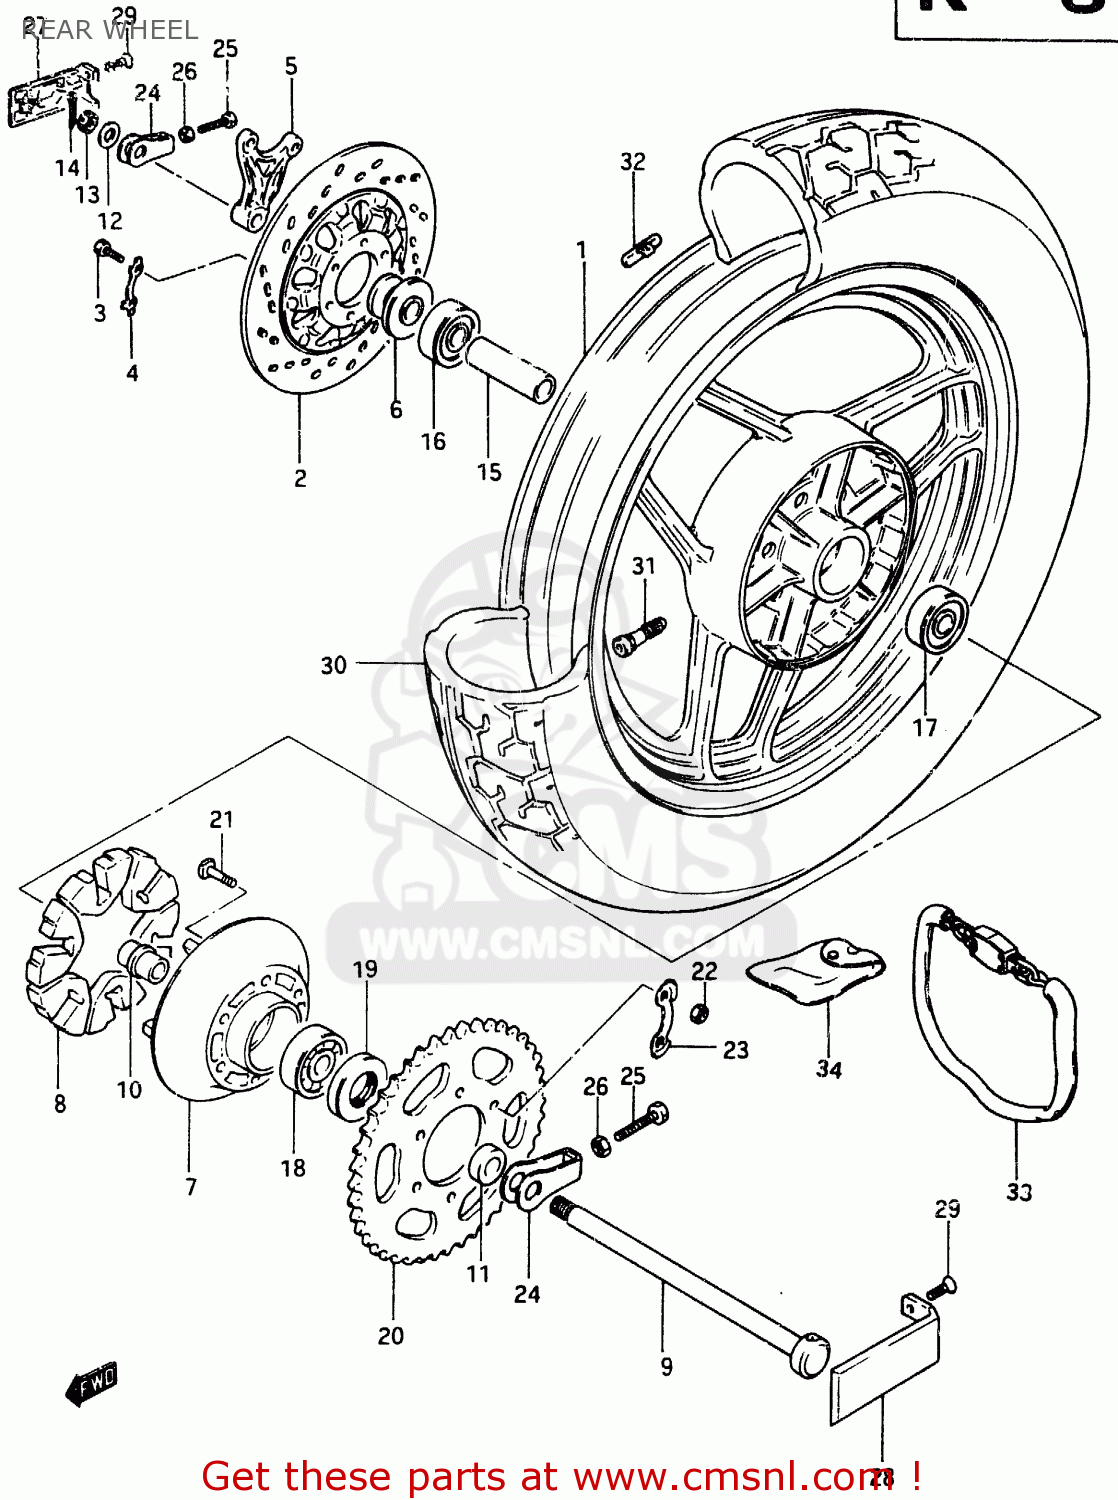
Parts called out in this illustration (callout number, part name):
1	CASTING WHEEL,GOLD
2	DISC,BRAKE
3	BOLT(8X30)
4	WASHER
5	BRACKET,REAR CALIPER
6	SPACER,REAR AXLE,RIGHT
7	DRUM,REAR SPROCKET MOUNT
8	ABSORBER,REAR HUB SHOCK
9	AXLE,REAR
10	RETAINER,RR SPROCKET DRUM
11	SPACER(17X33X11.3)
12	WASHER
13	NUT
14	PIN,COTTER
15	SPACER(17.5X25X88)
16	BEARING
17	BEARING
18	BEARING
19	SEAL,OIL(33X62X7)
20	SPROCKET,REAR
21	BOLT(10X35.5)
22	NUT
23	WASHER
24	ADJUSTER,CHAIN
25	BOLT 8X50
26	NUT
27	COVER,CHAIN ADJUSTER,R
28	COVER,REAR AXLE,LEFT
29	SCREW 5X16
30	TIRE, REAR (120/90-17 64H)
31	VALVE,TIRE
32	BALANCER,WHEEL
33	CHAIN LOCK ASSY
34	BAG,CHAIN LOCK
